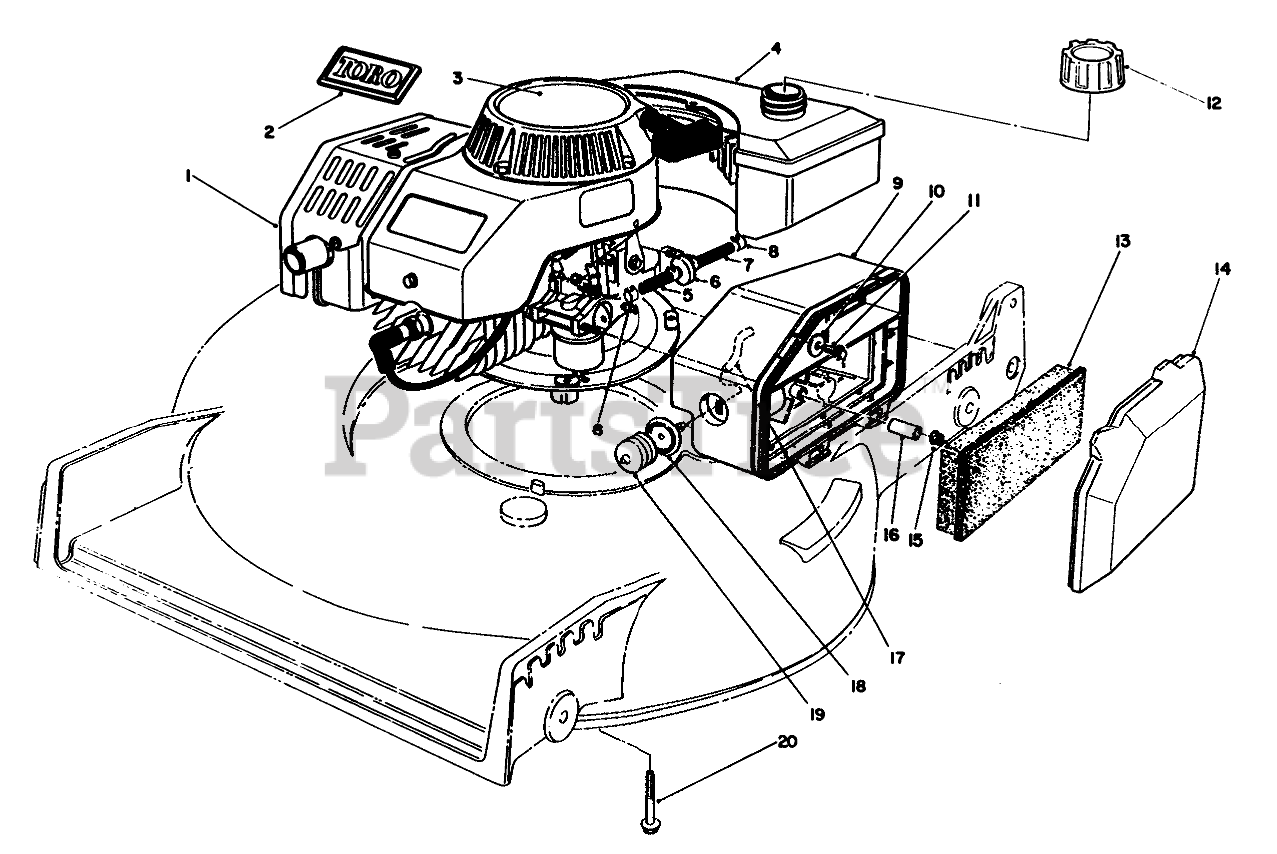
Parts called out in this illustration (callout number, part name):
1	Engine
2	TORO LOGO PLT
3	DECAL- 2 CYC RECOIL
4	Gas Tank Assembly
5	HOSE-FUEL
6	FILTER-FUEL
7	HOSE-FUEL
8	CLAMP-FUEL LINE
9	BODY-AIR CLEANER
10	WASHER-FLAT
11	SCREW-HH
12	GAS CAP ASM
13	ELEMENT-AIR CLEANER
14	COVER-AIR CLEANER
16	SPACER
17	HOSE-PRIMER
18	BODY-PRIMER
19	BULB-PRIMER
20	SCREW-HHF
